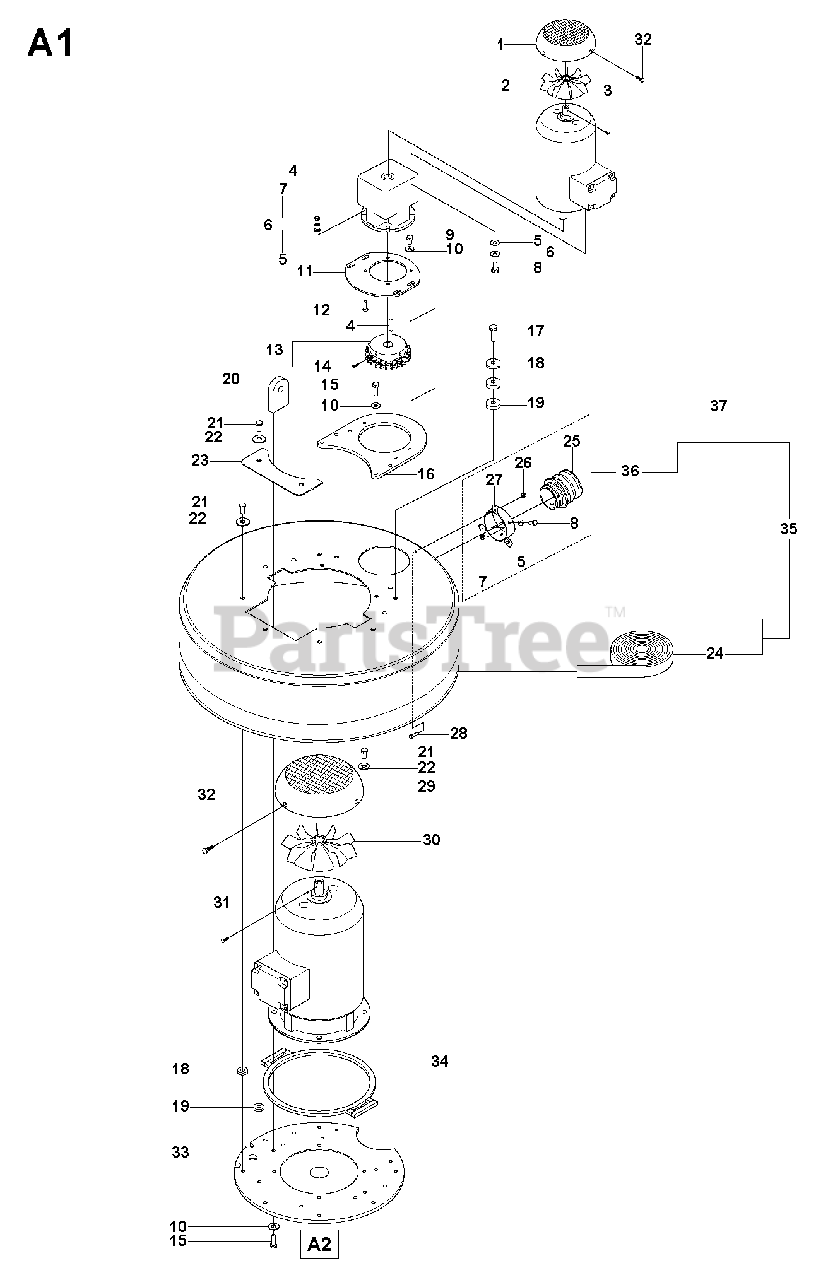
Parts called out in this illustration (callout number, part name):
5	WASHER
6	SPRING WASHER
7	HEXAGON LOCKING NUT
10	WASHER
22	WASHER
26	SCREW CRCSFM
28	HEXAGON LOCKING NUT
